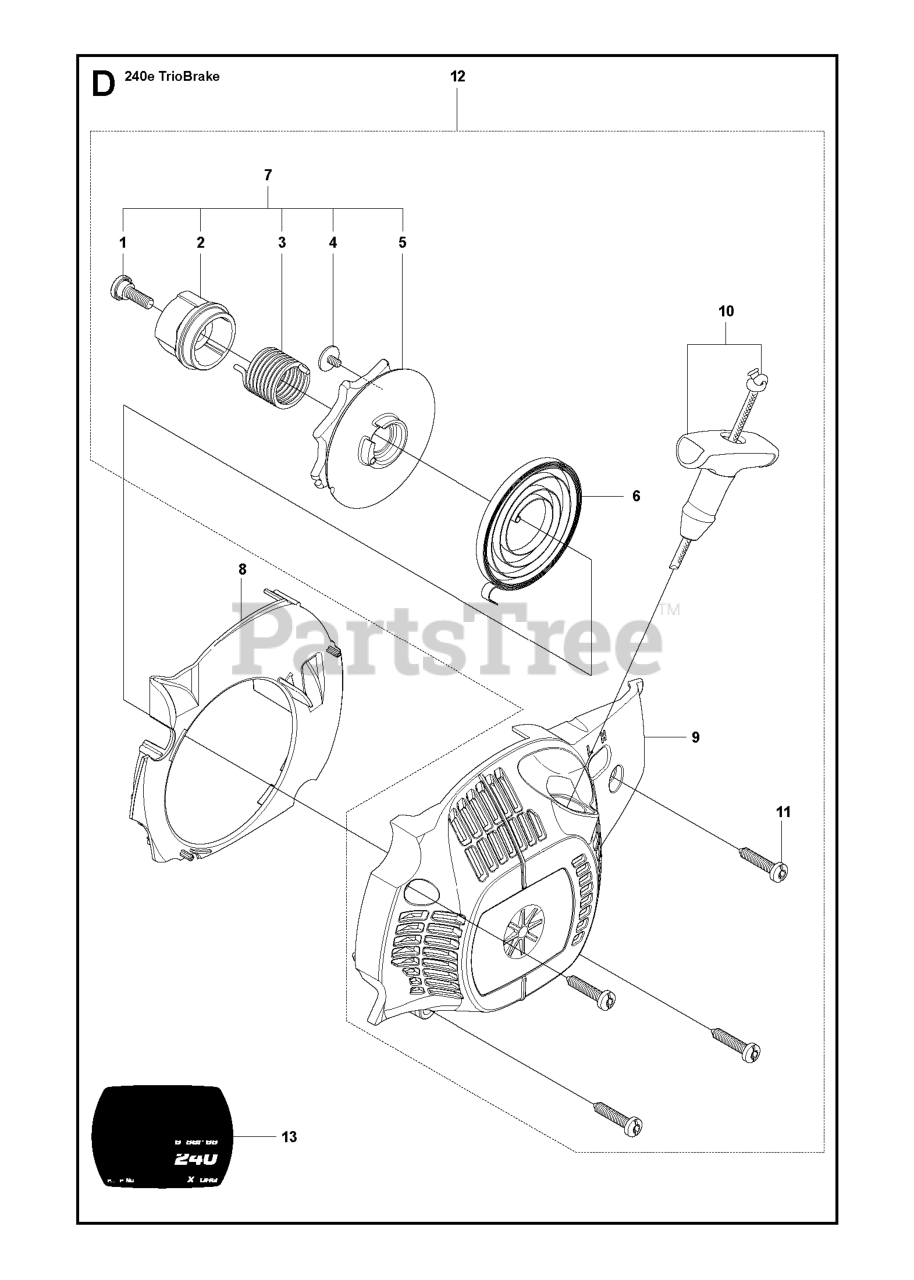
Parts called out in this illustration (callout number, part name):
1	SCREW SHOULDER
2	HUB STARTER EPS
3	SPRING EPS
5	PULLEY STARTER EPS
6	SPRING STARTER
7	KIT EPS STARTER
9	FAN HOUSING
10	STARTER ROPE W/HANDLE
11	SCREW M5.38-14X22.225MM
12	KIT COMPLETE EPS
13	DECAL 240E
